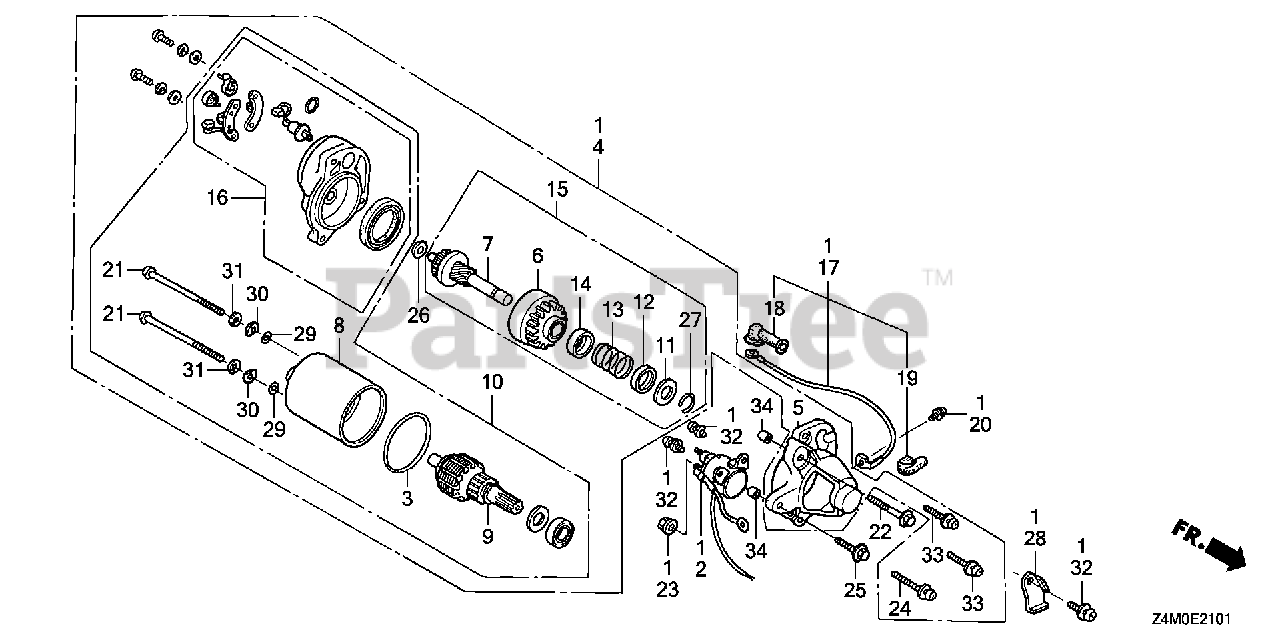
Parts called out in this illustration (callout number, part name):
1	MOTOR ASSY., STARTER
2	SWITCH, STARTING MAGNET
3	O-RING Use from Engine SN 2664637.
4	STARTER MOTOR UNIT (SM-11205) (181MM)
5	COVER, GEAR
6	PINION ASSY.
7	SHAFT UNIT, GEAR
8	YOKE ASSY.
9	ROTOR ASSY.
10	MOTOR ONLY
11	PIECE A, STOPPER
12	PIECE B, STOPPER
13	SPRING, RETURN
14	COVER, SPRING
15	GEAR ASSY.
16	BRACKET, FR.
17	WIRE, MAGNETIC SWITCH
18	COVER, STARTER MOTOR TERMINAL
19	COVER, MAGNET SWITCH TERMINAL
20	SCREW-WASHER (5X8)
21	BOLT, SETTING
22	BOLT, FLANGE (6X32)
23	NUT-WASHER (6MM)
24	SCREW-WASHER (5X30)
25	BOLT, FLANGE (6X25) Use up to Engine SN 2056819.
26	WASHER, PINION
27	CIRCLIP (10.2MM)
28	HOLDER, HARNESS
29	O-RING
30	WASHER, SPECIAL
31	WASHER, SPRING
32	SCREW-WASHER (5X14)
33	SCREW-WASHER (5X20)
34	PIN A, DOWEL (8X10)
